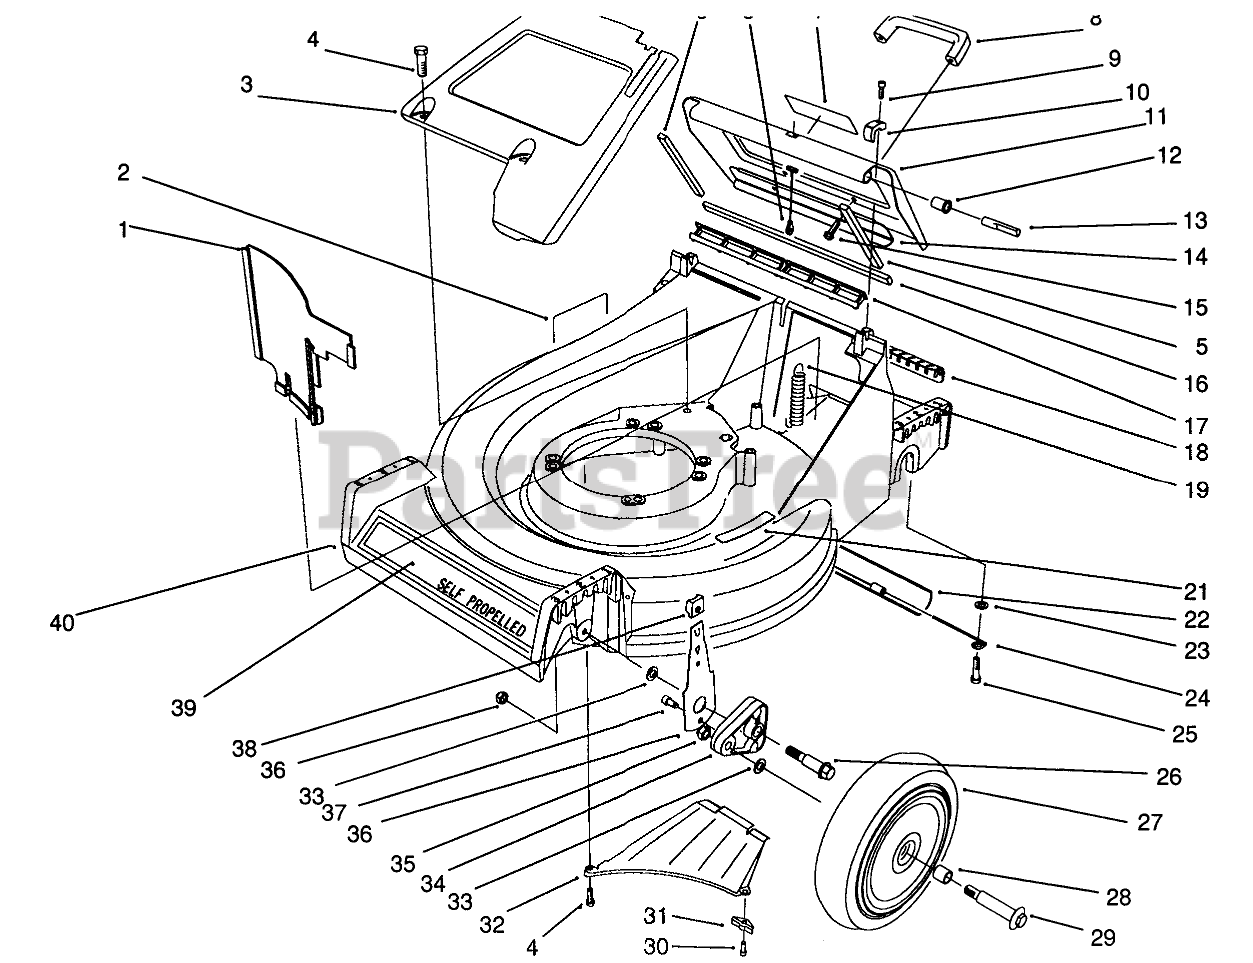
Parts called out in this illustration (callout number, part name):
1	PANEL-VERTICAL
2	DECAL-DANGER
3	PaneI-Screen
4	SCREW-HWHTF
5	DOOR SIDE SEAL
6	DOOR CABLE
7	DECAL - DANGER
8	HANDLE-DOOR
9	SCREW-HSH
10	HINGE CLAMP
11	Door-Discharge (Incl. Ref. #5, 7, 14 & 16)
12	DOOR BUSHING
13	HINGE PIN
14	DOOR - BRACE
15	SCREW-HWH
16	DOOR END SEAL
17	DOOR SEAL
18	ACCESS COVER
19	EXTENSION-SPRING
21	DECAL - STEP PAD INT'L
22	TRAILING SHIELD
23	WASHER-PLAIN
24	SHIELD HANGER
25	SCREW-SHOULDER
26	BOLT-SHOULDER
27	Wheel & Tire Assembly (Incl. Ref. #28)
28	BUSHING
29	WHEEL BOLT
30	SCREW-HWHTF
31	Bracket-Discharge
32	Ramp Discharge
33	WASHER
34	ARM-PIVOT, FRONT
35	NUT-LOCK
36	FRONT SPRING ARM ASM
37	SCREW-HSH, THREAD FORMING
38	KNOB-ARM
39	DECAL _ 21"
40	21" Housing Assembly (Incl . Ref . #2 & 21)
